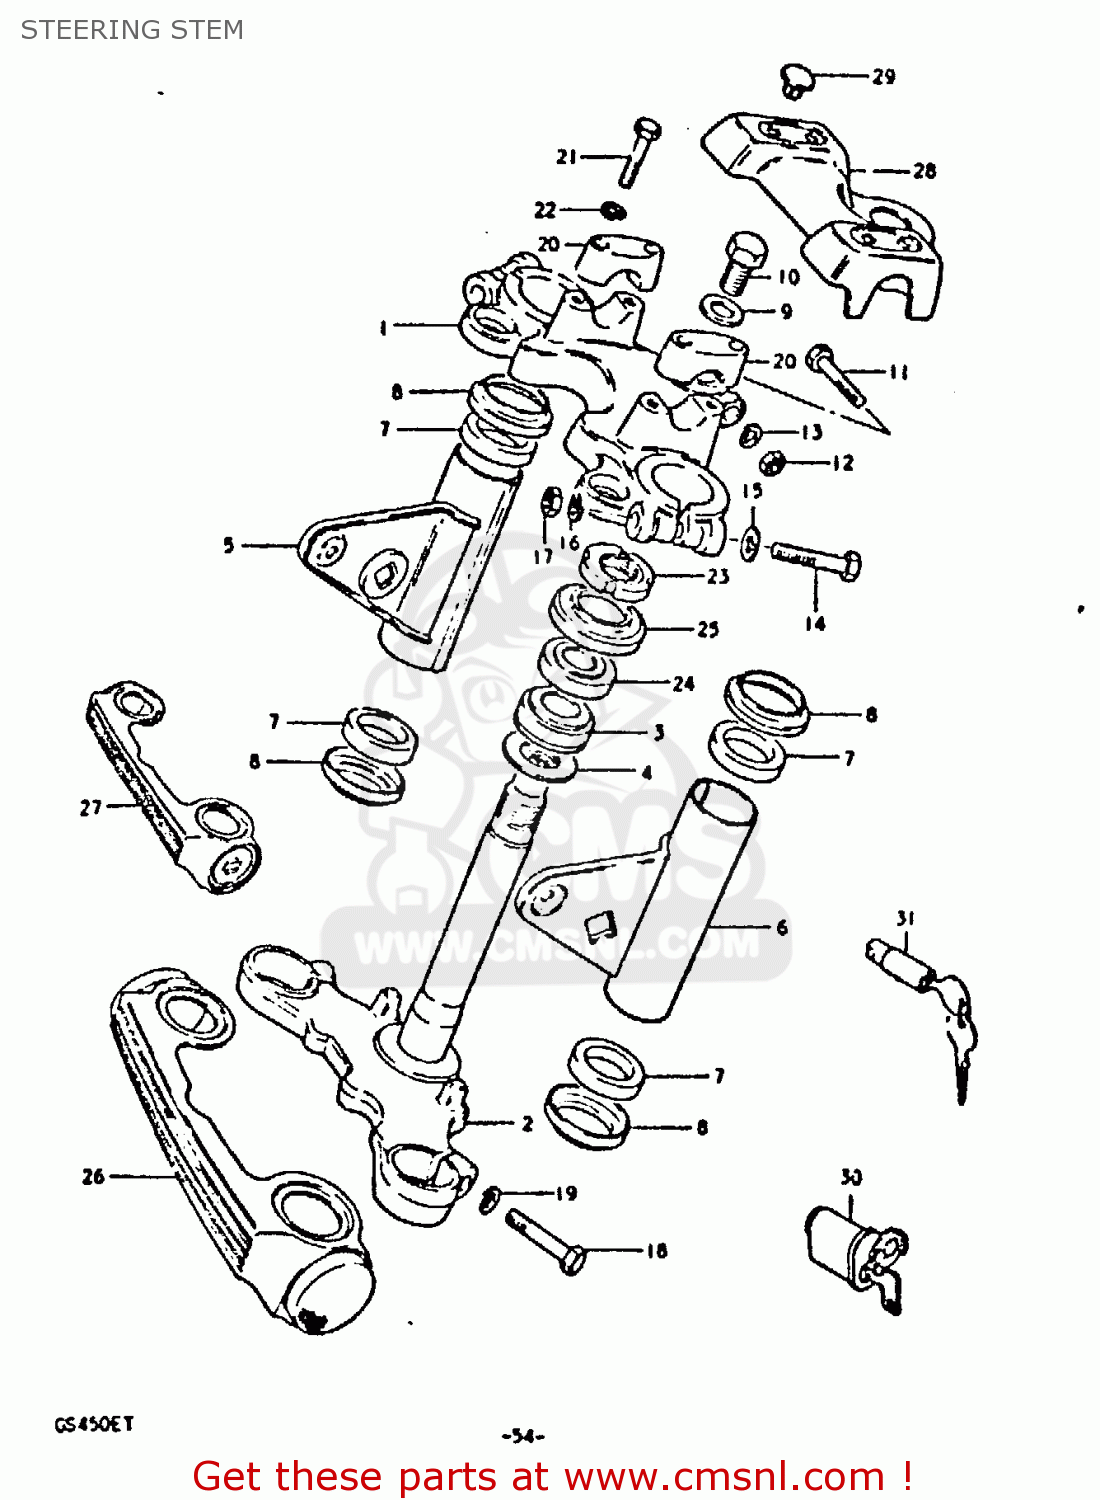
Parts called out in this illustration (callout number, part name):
1	HEAD,STEERING STEM
2	STEM,STEERING
3	BEARING
4	WASHER,THRUST
5	BRACKET,HEADLAMP,RIGHT
6	BRACKET,HEADLAMP,LEFT
7	CUSHION,HEADLAMP BRACKET
8	CAP,HEADLAMP BRACKET
9	WASHER
10	BOLT(12X20)
11	BOLT
12	NUT
13	LOCK WASHER
14	BOLT 10X55
15	WASHER
16	LOCK WASHER
17	NUT
18	BOLT 10X40
19	LOCK WASHER
20	HOLDER,HANDLE UPR
21	BOLT 8X35
22	LOCK WASHER
23	NUT,STEERING STEM(25X44X10)
24	TAPER,ROLLER BEARING
25	DUST SEAL,STEERING,UPPER
26	COVER,FR FORK
28	PAD,HANDLE
29	CAP(OD:19.5)
